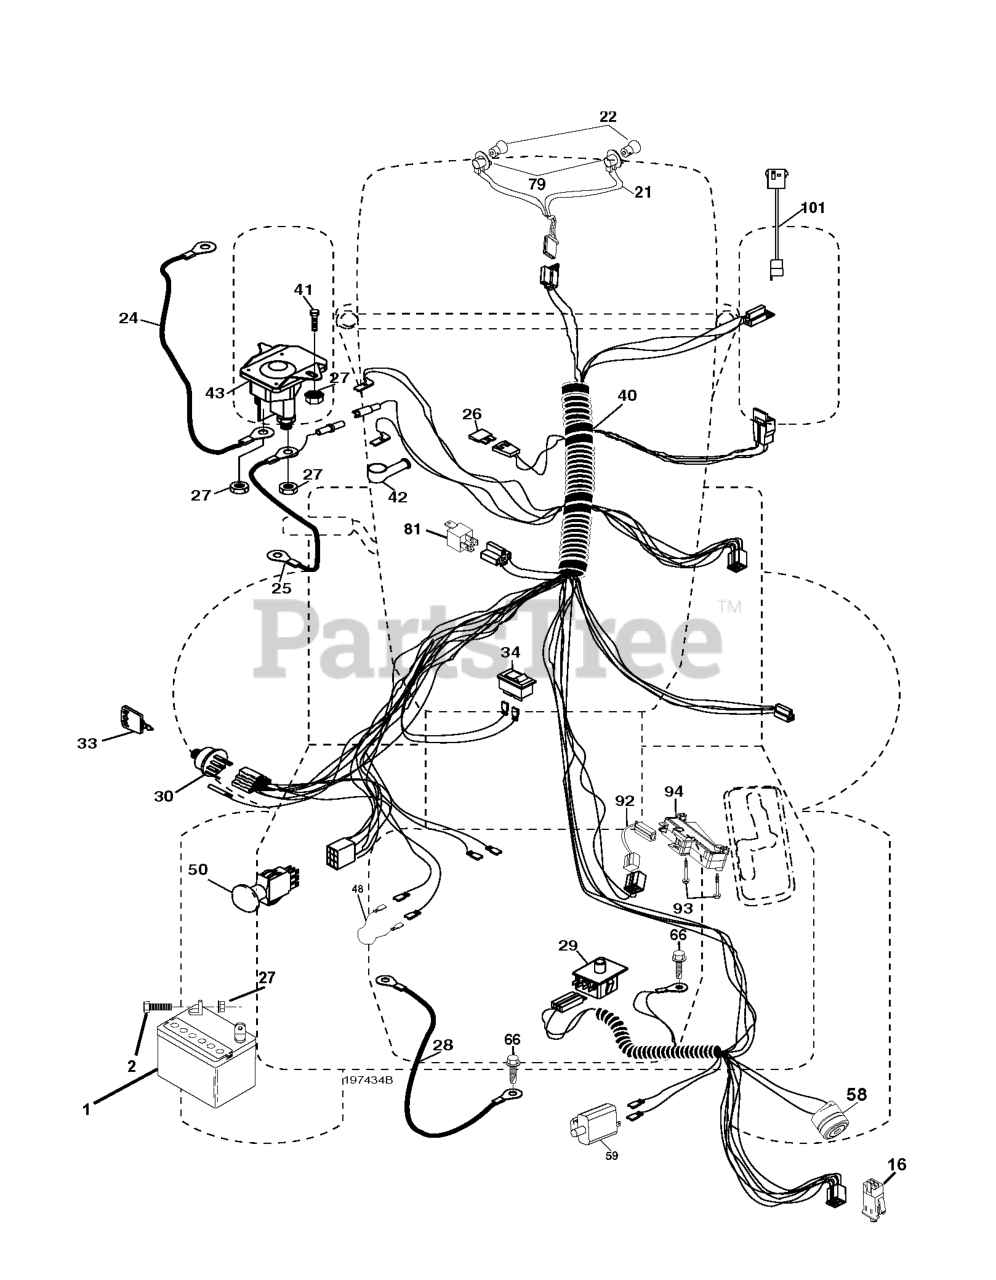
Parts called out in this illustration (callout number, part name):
1	BATTERY 12V .35 AMP
2	BOLT.HEX.1/4.X.3/4.DICHROMATE
16	SWITCH INTERLOOK PUSH-IN
21	HARNESS.LIGHT W/4152J BULBS
24	BATTERY CABLE GT
25	CABLE BATTERY
26	FUSE 20AMP
27	NUT
28	CABLE GROUND
29	SWITCH.SEAT.DP W/RAMPS
30	SWITCH.IGN.DELTA.W.LGH.ROS
33	KEY MLD GEN DELTA
40	RP HARNESS.IGN.ELECT.REG.CRD
41	BOLT
42	TERMINAL COVER
43	SOLENOID.W/BRASS.PLUNGER
48	ADAPTER.AMMETER
50	RP.PTO.SWITCH.8 TERMINAL.BLACK
58	BUZZER
59	.WITCH.FULL BAGGER.INDICATOR
79	BULB HOLDER ASM.
81	RELAY.ASSY.T
92	HARNESS.PIGTAIL.CONSLE
93	SCREW.PLASTITE
94	MODULE.REVERSE.ROS
101	PIGTAIL.MATNLK.NEW.HAR
